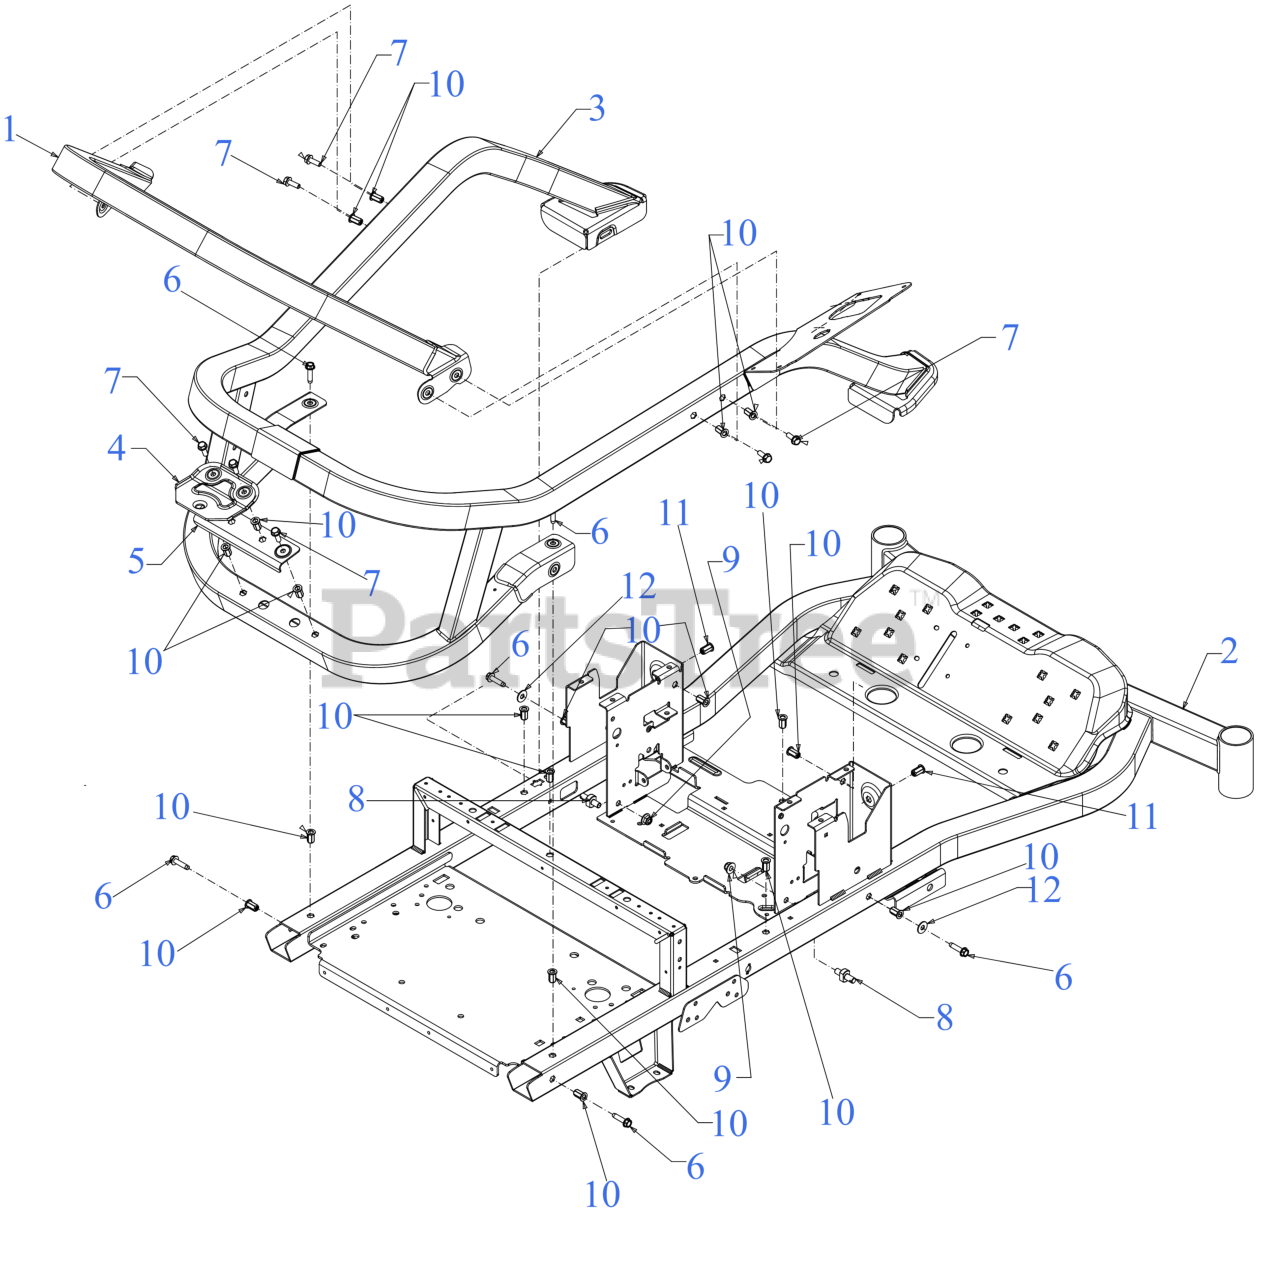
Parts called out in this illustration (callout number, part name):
1	UPPER FRAME HOOP
2	FRAME (LOWER)
3	FRAME (UPPER)
4	HITCH PLATE
5	HITCH MOUNT
6	SCREW 5/16-18 x 1.25
7	SCREW 5/16-18 x .875 GR5
8	SHOULDER STUD
10	NUT RIVET 5/16-18
11	NUT RIVET 5/16-18
12	FLAT WASHER
